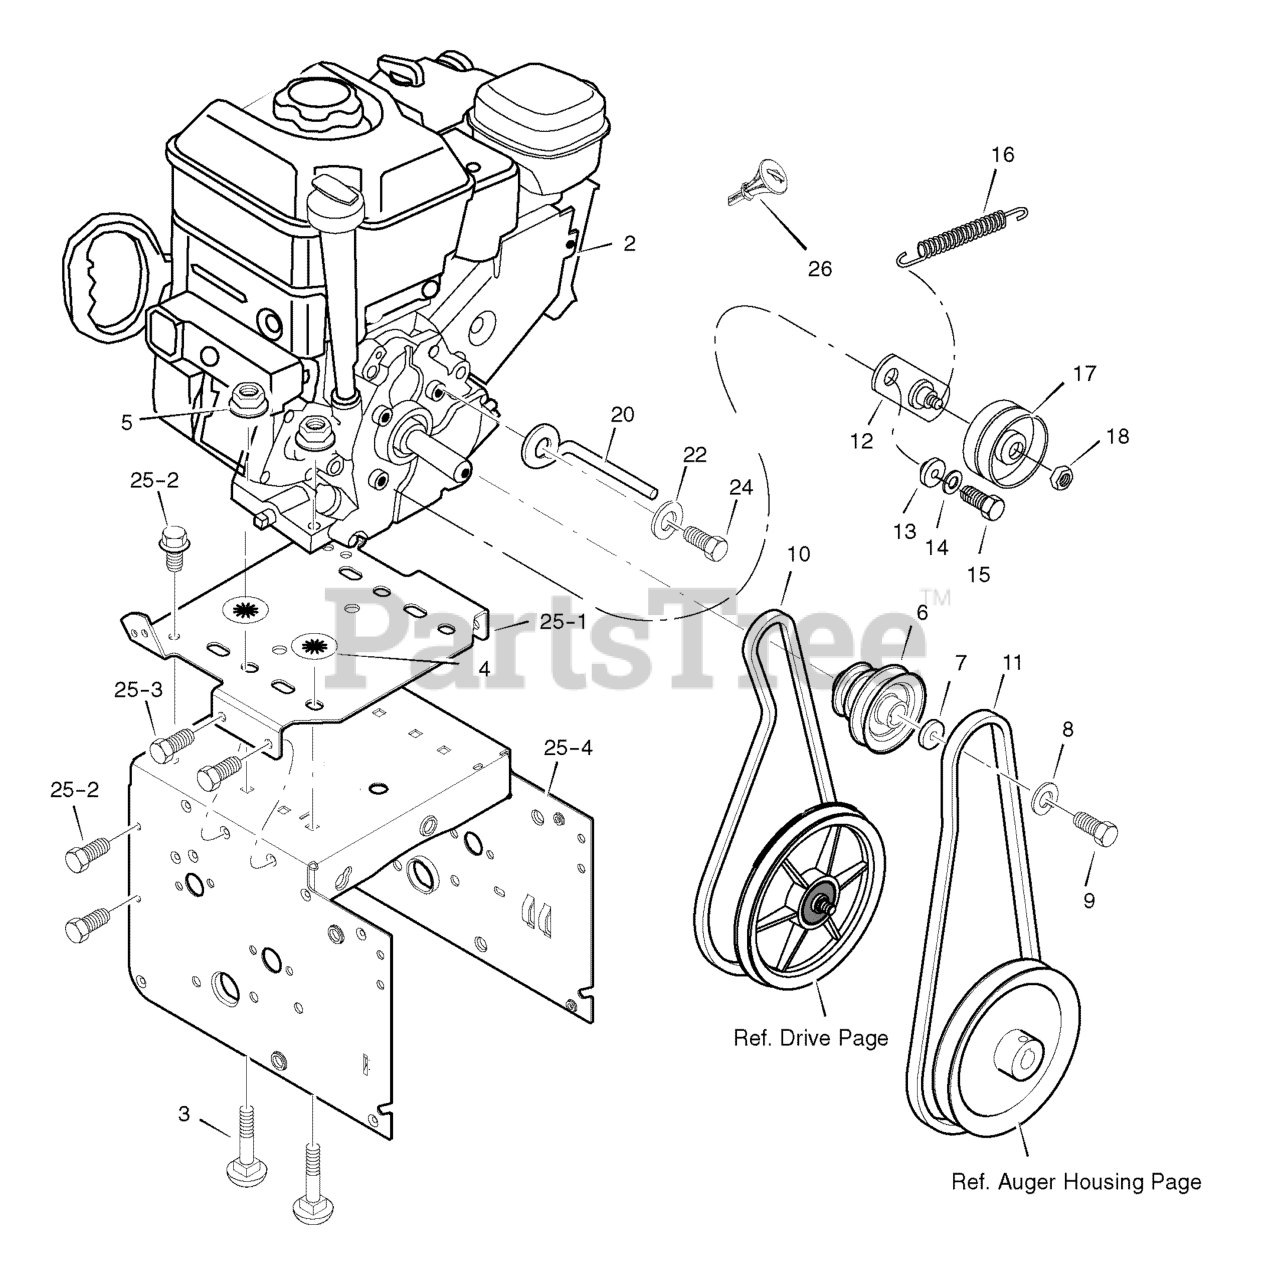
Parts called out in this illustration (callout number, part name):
2	ENGINE
3	BOLT, CARRIAGE 5/16-18
4	RETAINER, PUSH
5	NUT 5/16-18
6	PULLEY, ENGINE
8	WASHER .38ID
9	SCREW, 3/8-24 x 1.00
10	V-BELT, 3L, 33.13
11	BELT, V 4L
12	BRACKET ASSEMBLY, IDLER
13	BUSHING, IDLER BRACKET
14	WASHER, SPLIT
15	SCREW 5/16-24 X 0.75
16	SPRING, IDLER TRACTION DRIVE
17	PULLEY, IDLER
18	NUT, JAM 3/8-16
20	GUIDE, BELT
22	WASHER .31X.58X.08
24	SCREW, 5/16-24 x 0.75
25-1	PLATE, ENGINE MOUNT
25-2	SCREW, TAP 1/4-20 X .63
25-3	SCREW, TAP 5/16-18 X .50
25-4	FRAME, MOTOR BOX
26	KEY, BRIGGS ENGINE
